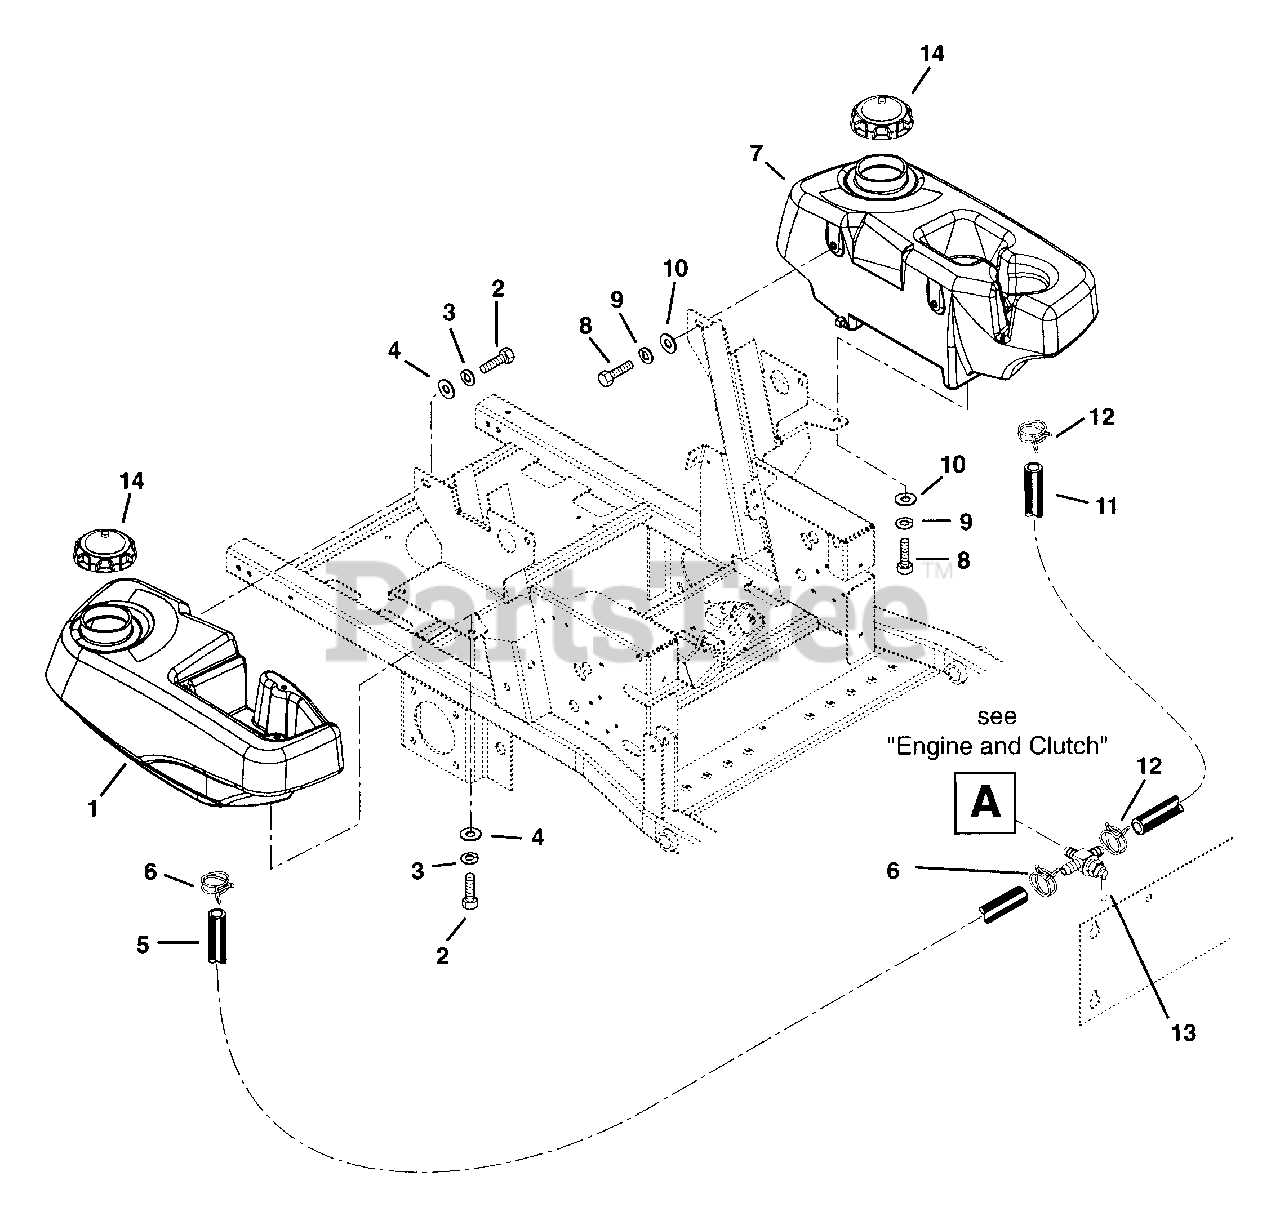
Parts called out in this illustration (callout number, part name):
1	Fuel Tank Right-Hand
1	Fuel Tank Fitting
2	Bolt-Hex .31-18 x .75 Grade 5
3	Washer-Locking .31 x .078
4	Washer-Flat-Steel .38 x .875 x .083
5	Gas Line-Bulk 1/4" ID
6	Hose-Clamp
7	Fuel Tank Left-Hand
7	Fuel Tank Fitting
8	Bolt-Hex .31-18 x .75 Grade 5
9	Washer-Locking .31 x .078
10	Washer-Flat-Steel .38 x .875 x .083
11	Gas Line-Bulk 1/4" ID
12	Hose-Clamp
13	Valve-Fuel
14	Cap-Gas
